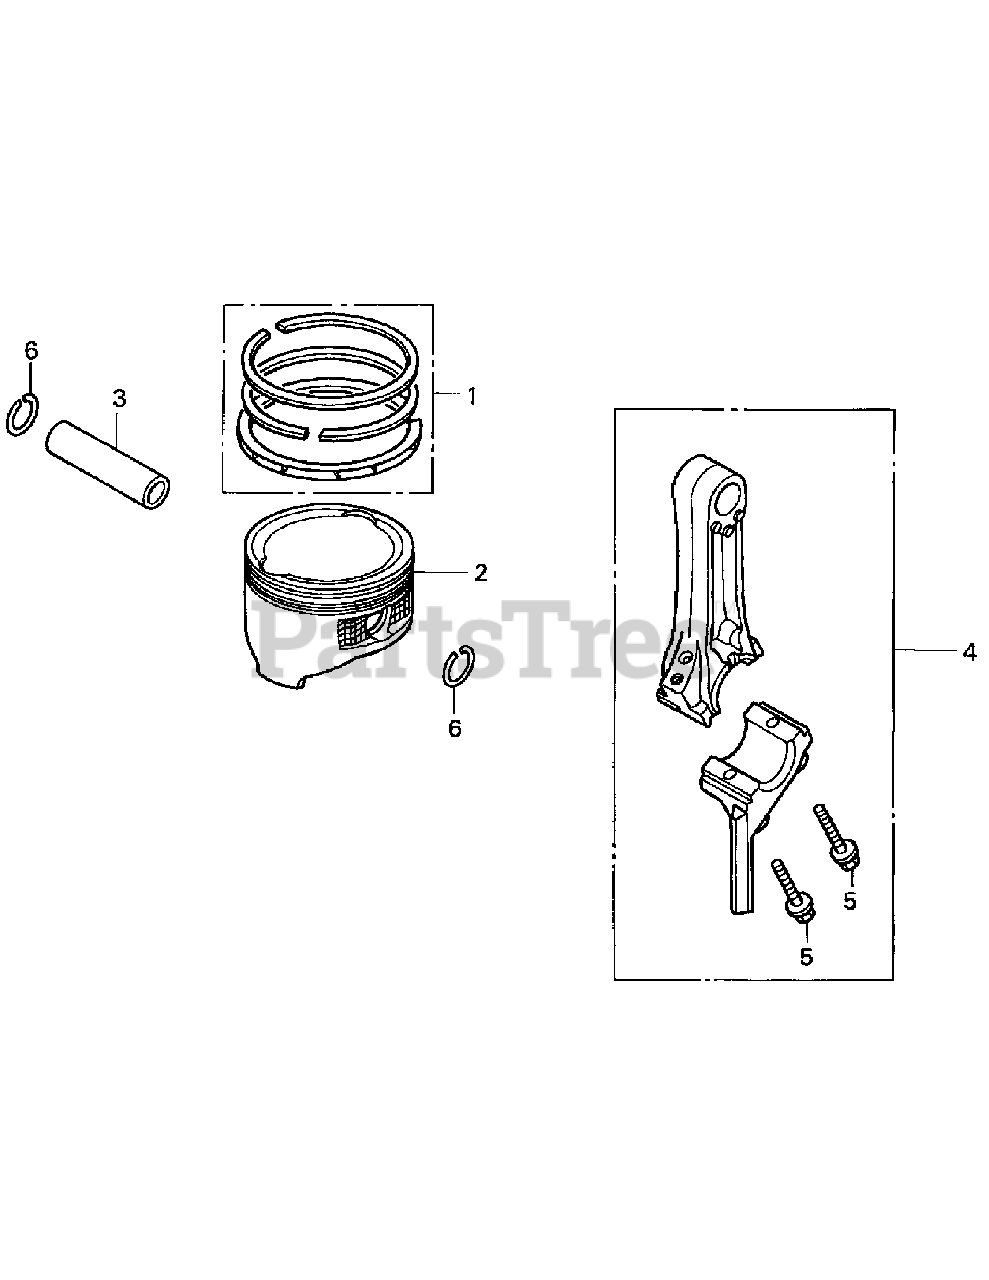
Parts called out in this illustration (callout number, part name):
1	RING SET, PISTON (RIKEN)
1	RING SET, PISTON (TEIKOKU)
3	PIN, PISTON
4	ROD ASSY., CONNECTING
5	BOLT, CONNECTING ROD
6	CLIP, PISTON PIN (13MM)
